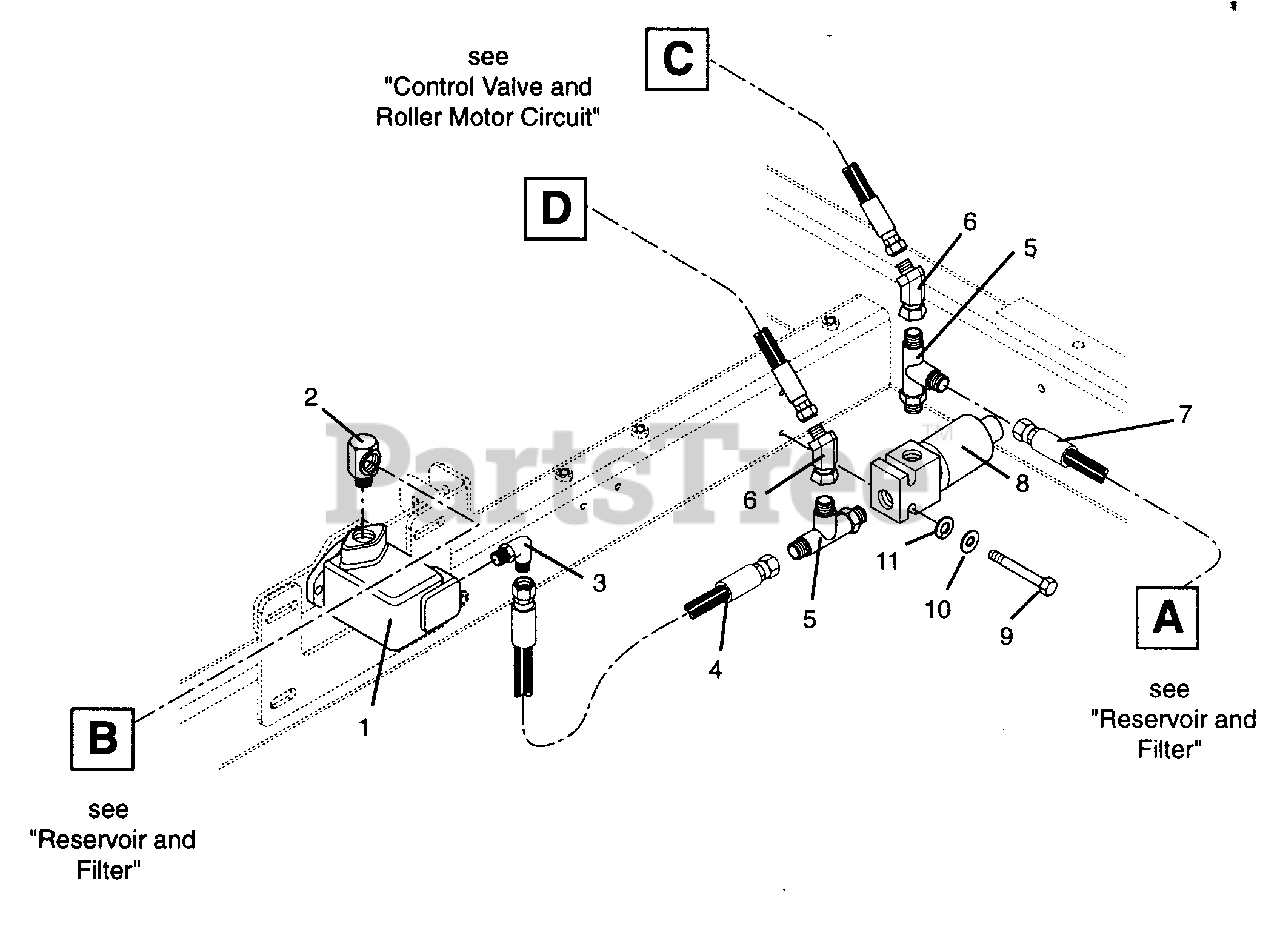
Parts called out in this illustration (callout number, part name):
1	Pump - Hydraulic
2	Hydraulic Fitting-Swivel
3	Adapter-Pipe .75-16 O-Ring
4	Hydraulic Hose
5	Hydraulic Fitting-Tee O-Ring
6	Adapter-45 Degree Swivel Elbow 37 DegreeFlare Tube
7	Hose-Hydraulic
8	Hydraulic Valve
9	Bolt-Hex .25-20 x 2.50
10	Washer-Flat-Steel .312 x .734 x .065
11	Washer-Lock .250 x .077
